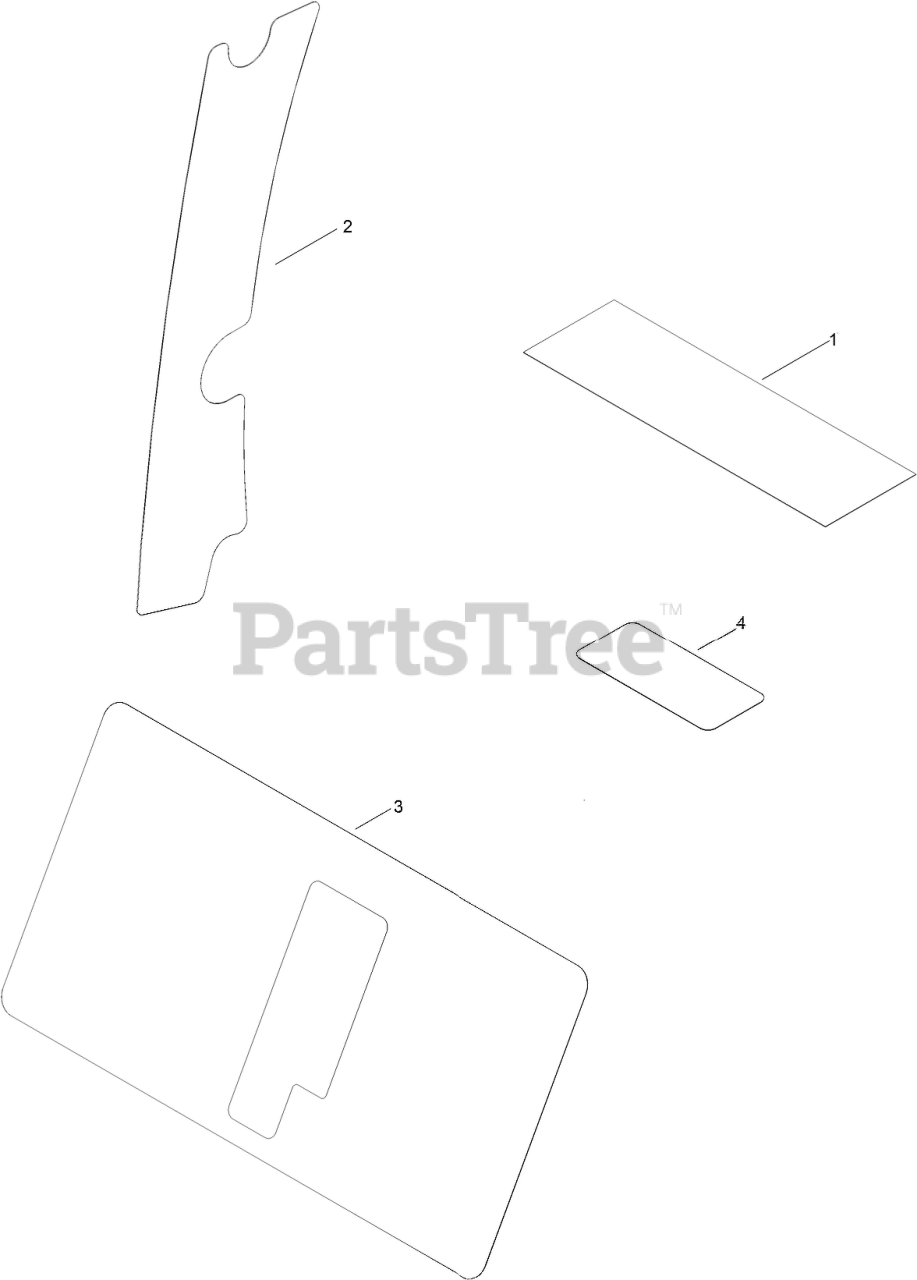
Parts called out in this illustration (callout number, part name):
1	DECAL-SERVICE, CE
2	DECAL-HOC
3	DECAL-CONTROL, SPEED
4	DECAL-LOCATION, SERVICE DEALER
